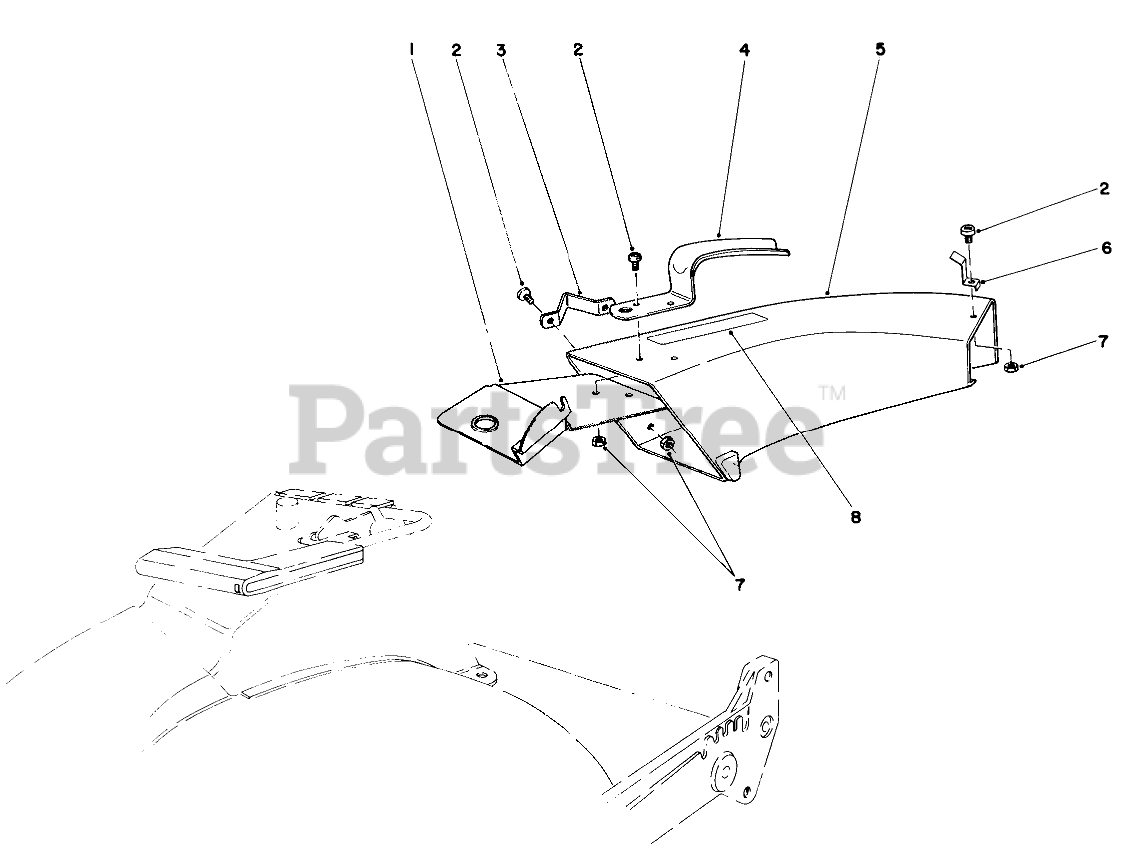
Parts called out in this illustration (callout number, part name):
1	Plate-Discharge Chut
2	10-24 X 5/8 PAN HD MS
3	SIDE BRACKET
4	CHUTE HANDLE
5	Chute-Discharge (Incl. Ref. #8)
7	NUT-LOCK, NI
8	DECAL CAUTION
